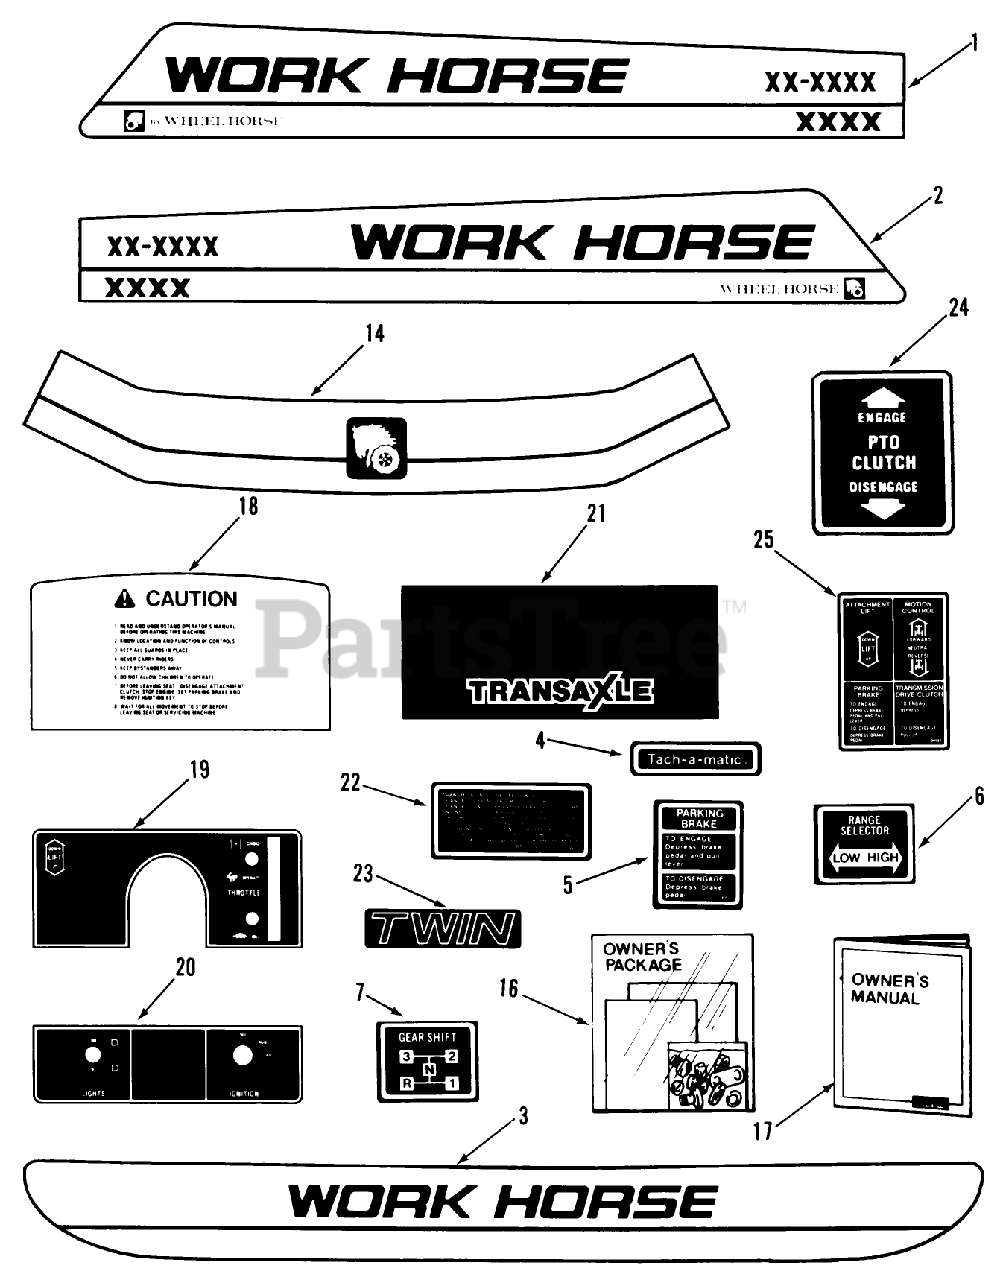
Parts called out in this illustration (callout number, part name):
5	DECAL-PARKING BRAKE
6	DECAL, RANGE SELECTOR
17	Owner-s Manual-Tractor
